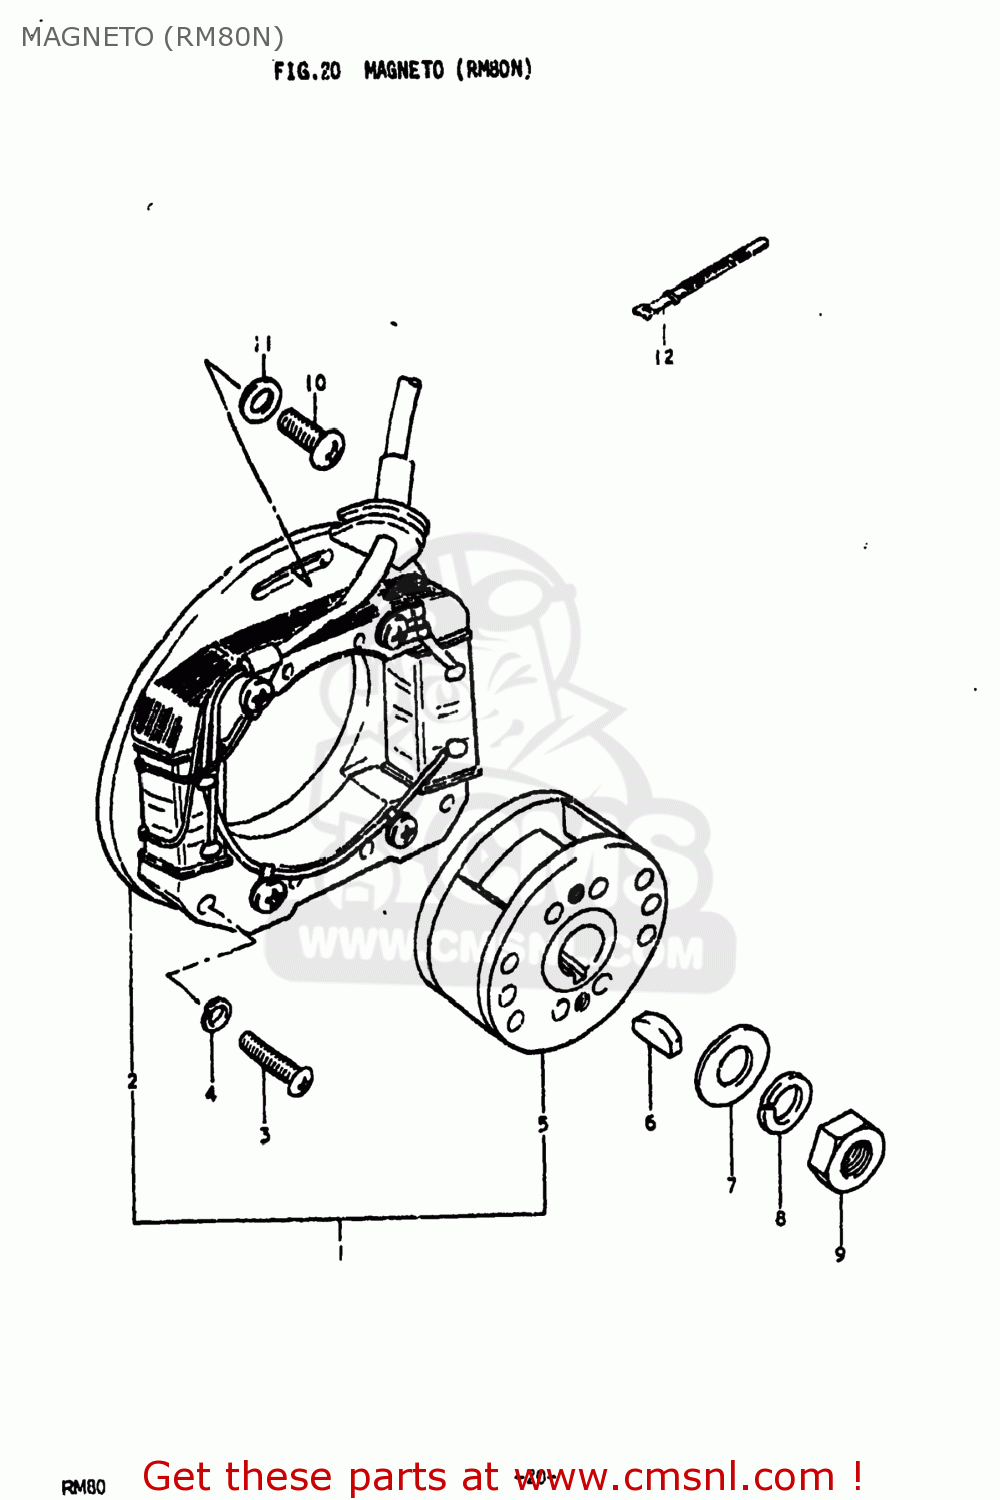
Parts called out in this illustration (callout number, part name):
1	MAGNETO ASSEMBLY
2	STATOR ASSEMBLY
3	SCREW 5X20
4	LOCK WASHER
5	ROTOR ASSEMBLY
6	KEY 4MM
7	WASHER
8	LOCK WASHER
9	NUT (10MM)
10	SCREW
11	WASHER
12	CLAMP
